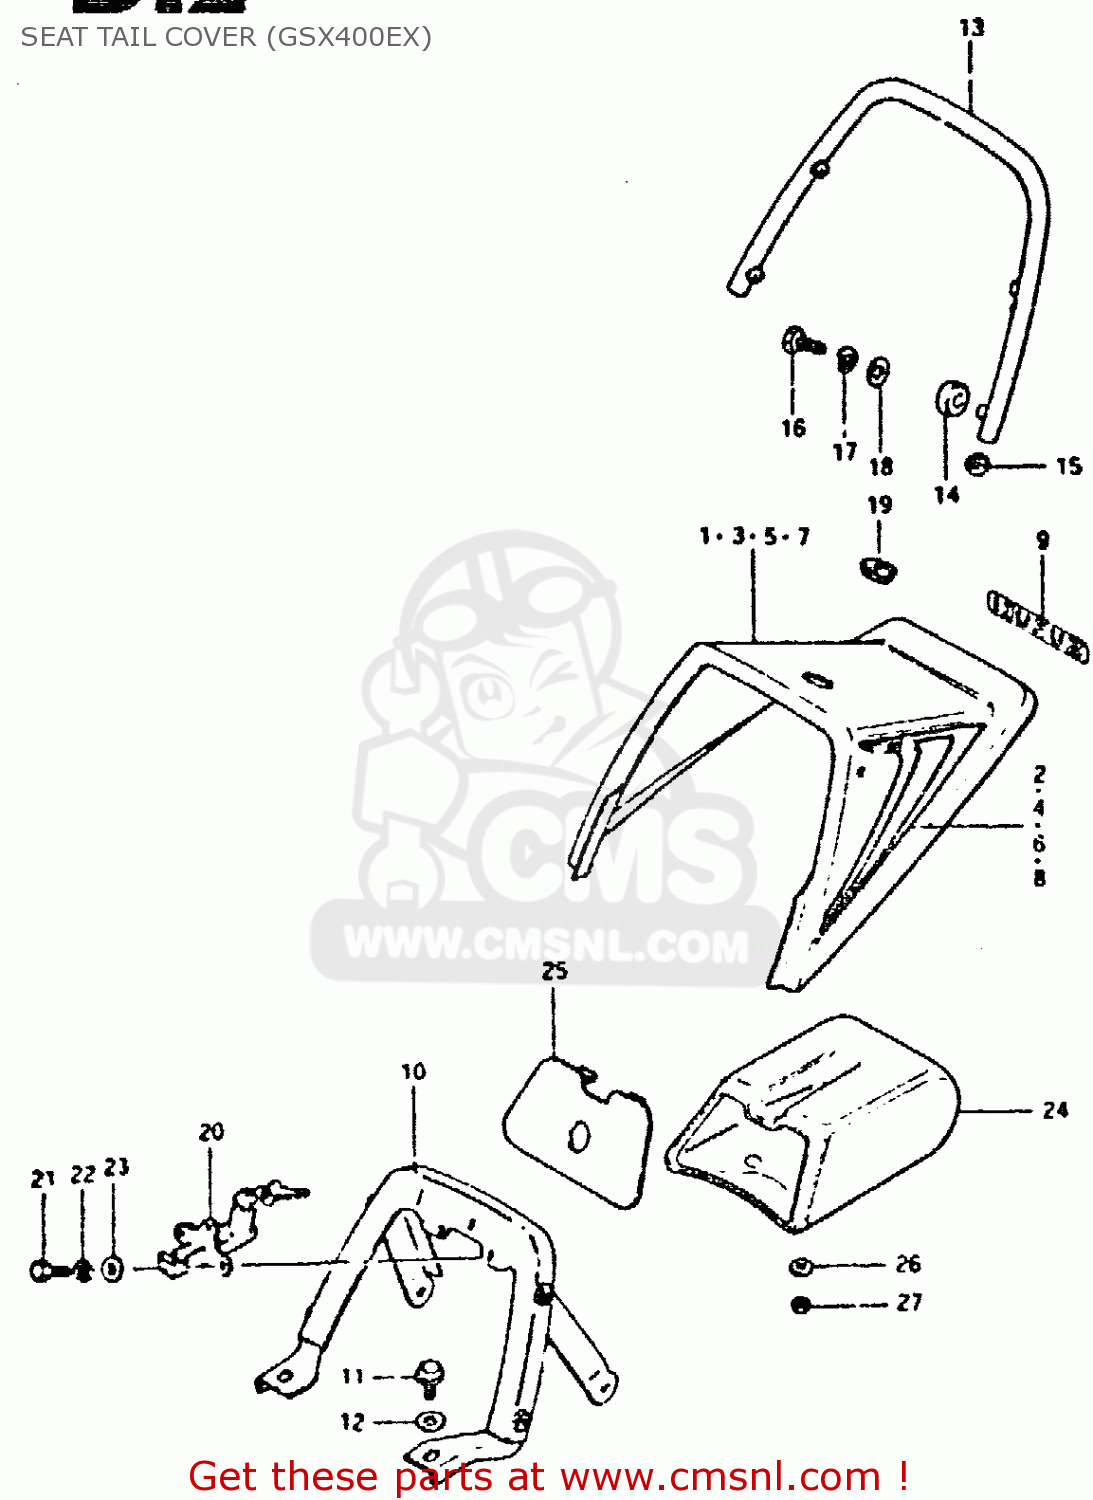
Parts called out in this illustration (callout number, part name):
1	COVER,SEAT TAIL
2	TAPE SET
3	TAIL COVER, SEAT (BLUE)
4	TAPE SET
5	COVER,SEAT TAIL
6	TAPE SET
7	COVER,SEAT TAIL
8	TAPE SET
9	EMBLEM,SEAT TAIL COVER
10	BRACKET, SEAT TAIL COVER
11	BOLT
12	WASHER (8.7X22X2)
13	HANDLE,PILLION RIDER
14	CUSHION
15	END,SHEET HANDLE
16	BOLT (8X30)
17	LOCK WASHER
18	WASHER
19	GROMMET,SEAT LOCK HOLE
20	LOCK SET,SEAT
21	BOLT
22	LOCK WASHER
23	WASHER
24	BOX, SEAT TAIL
25	LID,SEAT TAIL BOX
26	WASHER
27	NUT 6MM
